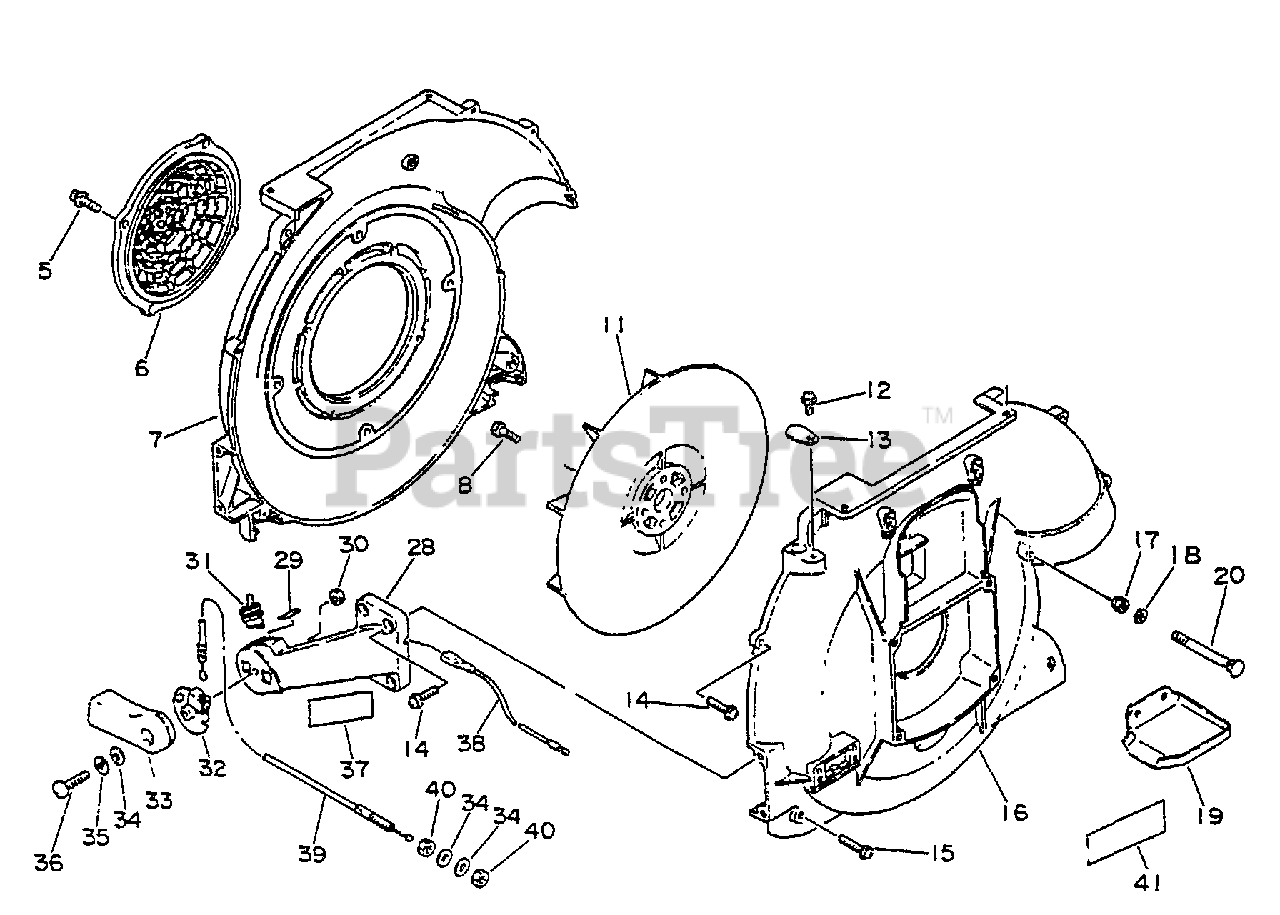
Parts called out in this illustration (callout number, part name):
6	SHIELD, DEBRIS
7	COVER, FAN - INNER -- ORANGE
8	BOLT - 6×16
12	SCREW 5×10
14	SCREW 5×20
15	SCREW 5×25
16	COVER, FAN - OUTER
17	NUT - 5 -- CAP
18	SCREW 5×25
19	BRACKET, MUFFLER COVER
28	MOUNT, THROTTLE LEVER
29	LABEL, ON-OFF
30	NUT, HEX M6
31	IGNITION SWITCH ASSY
33	CONTROL, THROTTLE
35	WASHER, SPRING 6
36	SCREW 6×25
37	LABEL - CAUTION
39	CABLE, THROTTLE
41	LABEL - NOISE
